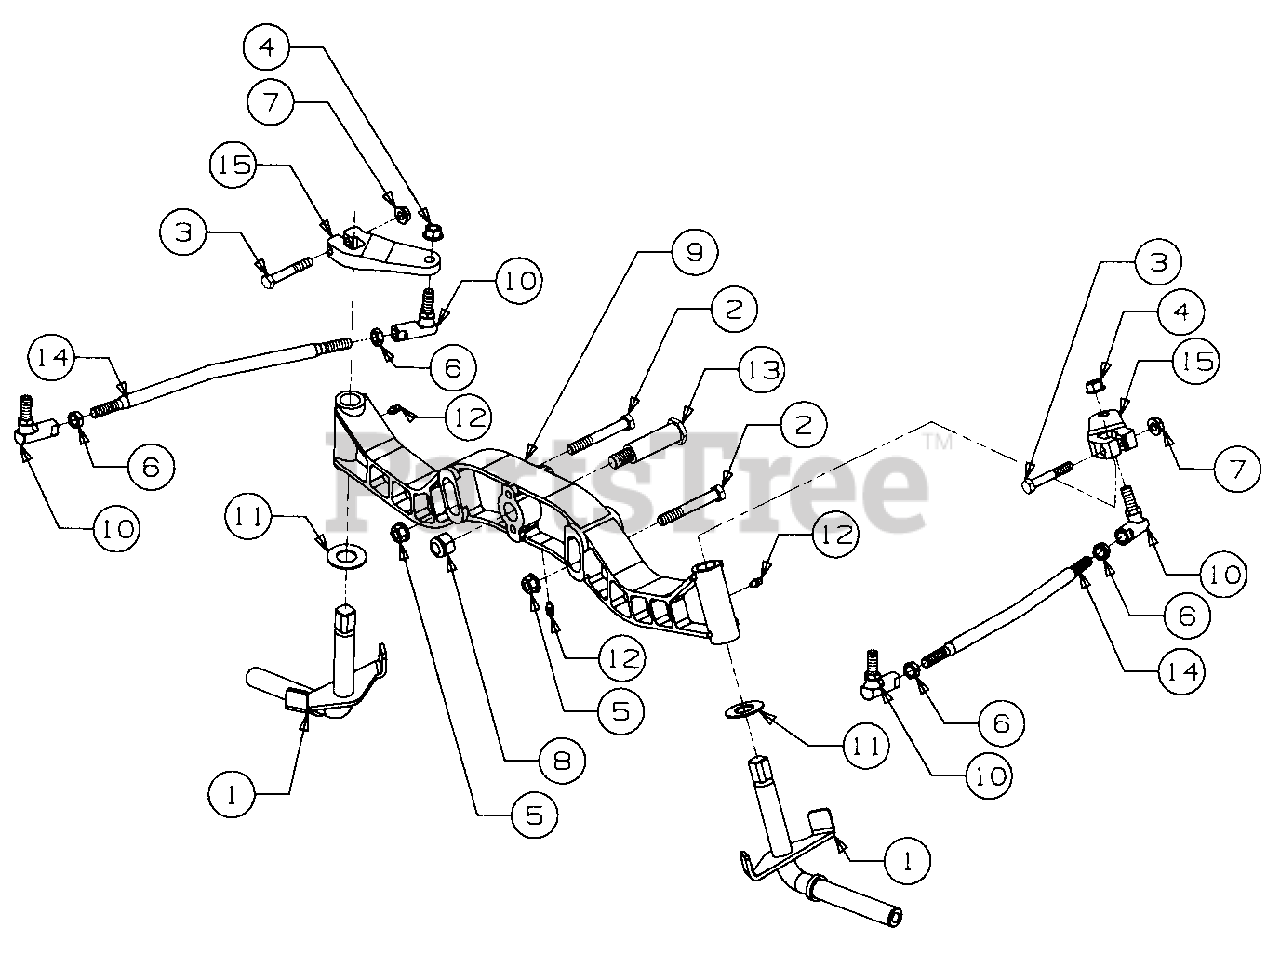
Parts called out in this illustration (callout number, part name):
1	Knuckle Assembly, Steering
2	Screw, Hex Cap, 3/8-16 x 2.75 GR8
3	Screw, Hex Cap, 5/16-18 x 2 GR5
4	Nut, Hex Lock, 3/8-24 GR5
5	Nut, Hex Flanged Lock, 3/8-16
6	Nut, Hex Jam, 3/8-24 GR2
7	Nut, Hex Flange Top Lock, 5/16-18
8	Nut, Hex Top Nylon Lock, 1/2-13
9	Axle, Front Pivot
10	Joint, Ball, 3/8-24
11	Washer, Flat, .760 x 1.49 x .06 Thk.
12	Fitting, Lube, 3/16 Drive Type
13	Bolt, Pivot Shoulder, 3/4 Dia x 2.23
15	Arm, Steering
